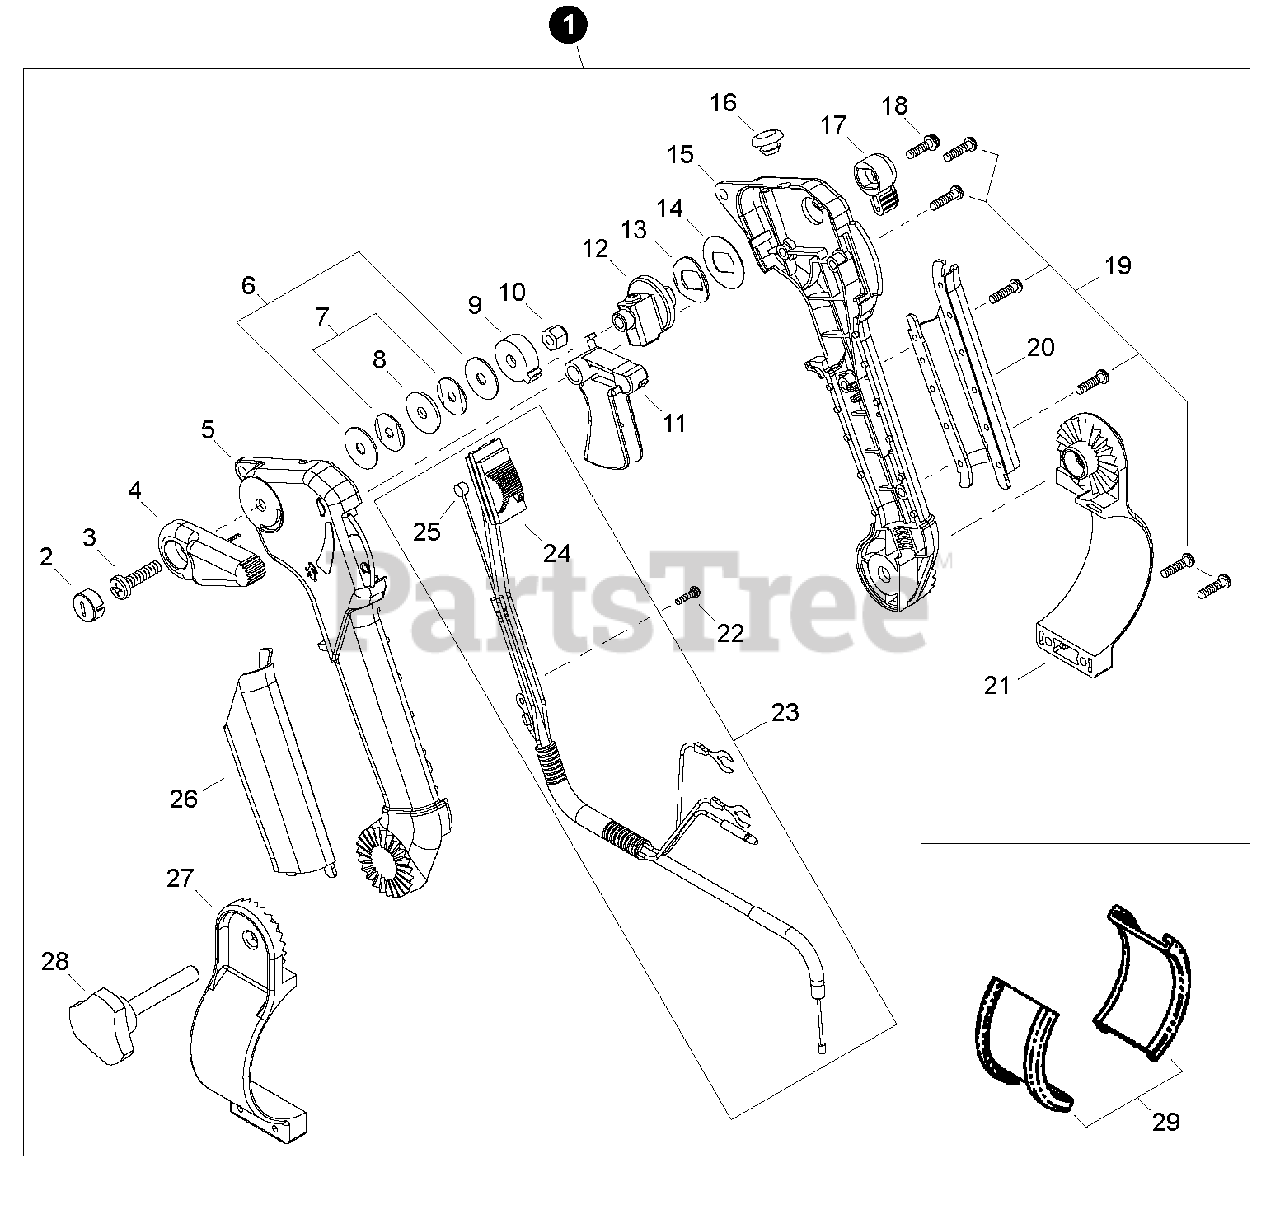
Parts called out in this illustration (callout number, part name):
1	THROTTLE CONTROL ASSY
2	CAP, BOLT
3	BOLT M6×25
4	CONTROL, THROTTLE
5	CONTROL HANDLE - LEFT
6	WASHER M6
7	WASHER, SPRING
8	WASHER M6
9	LEVER, THROTTLE
10	NUT, NYLON M6
11	TRIGGER, THROTTLE
12	LIMITER ASSY, THROTTLE
13	WASHER, WAVE
14	WASHER
15	CONTROL HANDLE - RIGHT
16	PLUG, THROTTLE LIMITER
17	LEVER, THROTTLE LIMITER
18	SCREW M4×16
19	SCREW M4×16
20	GRIP, RIGHT
21	BRACKET, RIGHT
22	SCREW M3×8
23	CABLE ASSY, CONTROL
24	SWITCH, ON-OFF
25	CABLE, THROTTLE
26	GRIP, LEFT
27	BRACKET, LEFT
28	KNOB, SCREW
29	SPACER
